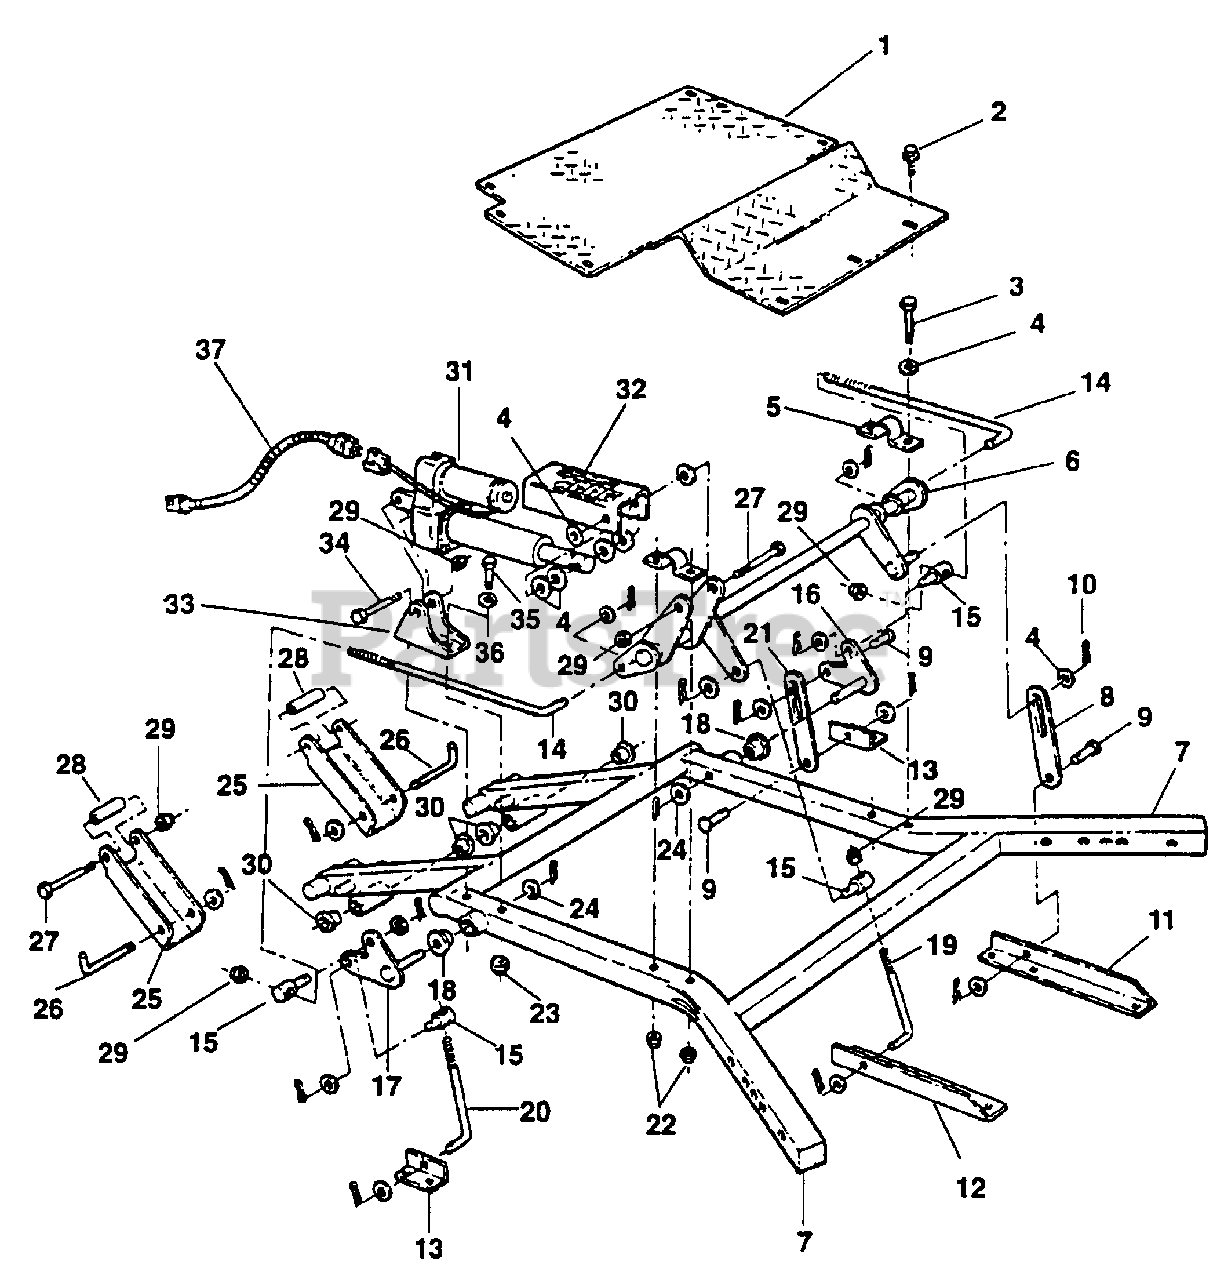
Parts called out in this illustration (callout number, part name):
1	PLATE, Diamond Tread Foot
2	SCREW, 5/16-18 x 5/8" Hex Self-Tapping
3	BOLT, 5/16-18 X 2-1/2" GD5 YZ
4	WASHER, .531 x 1.062 x .121 SAE Flat
5	BRACKET, Deck Lift Hanger
6	ARM, Front Lift (Weldment)
7	FRAME, Deck (Weldment)
8	BAR, 7" Lift
9	PIN, 1/2 x 1 1/8" Clevis (YZ)
10	PIN, 5/32 x 1" Cotter
11	ANGLE, Front Deck Mounting (L.H.)
12	ANGLE, Front Deck Mounting (R.H.)
13	BRACKET, Deck Lift, Rear
14	ROD, Timing, 1/2" Threaded
15	SWIVEL, .50 Thru Hole
16	ARM, Rear Bellcrank (L.H.) (Weldment)
17	ARM, Rear Bellcrank (R.H.) (Weldment)
18	BEARING, .75 I.D.
19	J-BOLT, 1/2" Dia. x 8 1/2" Long (Front)
20	J-BOLT, 1/2" Dia. x 7" Long (Rear)
21	BAR, 5.62 Lift
22	NUT, 5/16-18 HEX NYLON LOCK
23	NUT, 3/8-16 HEX NYLON LOCK
24	WASHER, 13/16 x 1 15/32" (HS)
25	CHANNEL, Deck Stabilizer
26	J-BOLT, Deck Attachment
27	BOLT, 1/2-13 x 4" Hex (HO)
28	SLEEVE, Stabilizer
29	NUT, 1/2-13 HEX NYLON LOCK
30	BUSHING, Suspension
31	LINEAR ACTUATOR, 1000 Lbs., 4" Stroke
32	INDICATOR, Height Of Cut
33	BRACKET, Actuator Anchor
34	SCREW, 1/2 UNC x 2.5 Hex Head Cap
35	BOLT, 3/8-16 X 2-1/2" GD5 CZ
36	WASHER, 3/8" Flat
37	WIRE HARNESS, Deck Lift
